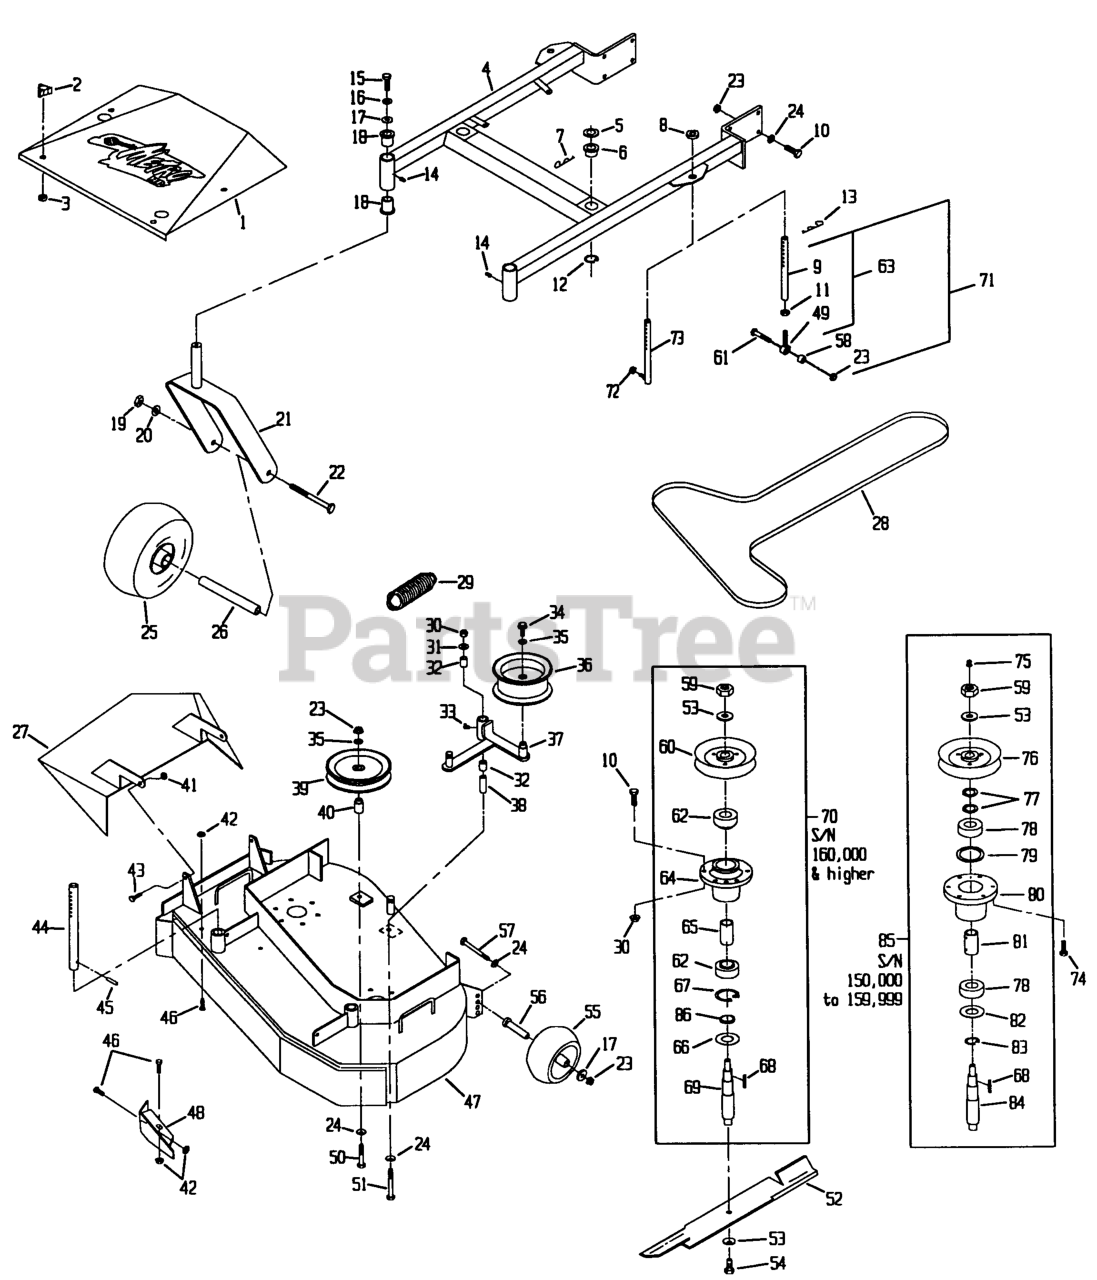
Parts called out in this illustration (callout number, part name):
1	SHIELD W/DECAL,MHP36
2	KNOB-3 PRONG
4	DECK SUPPORT W/BSHGS 36"
5	SPACER-DECK SUPPORT
6	BUSHING-DECK
9	LINK, DECK SUPPORT
13	PIN,HAIR COTTER
18	BEARING-FLANGED
28	BELT,DECK DRIVE
32	SLEEVE-BEARING
38	BUSHING-PIVOT, IDLER
39	PULLEY-IDLER
40	BUSHING-IDLER
44	ROD,DECK SUPPORT
47	ASM,DECK W/DECALS TTHP/MH
49	BALLJOINT
51	SCREW-HH
53	WASHER-SPRING
55	ROLLER-SCALP, ANTI
56	BUSHING-ROLLER
60	SHEAVE,W/HUB 5.72
62	BEARING
65	SPACER-BEARING
66	GUARD-BEARING, BOTTOM
68	KEY-RECTANGLE
69	SHAFT,SPINDLE
70	HOUSING,CUTTER COMPLETE
73	Link
74	SCRW,TPTTE HH
76	SHEAVE,W/HUB 5.72
77	WASHER-SPACER
78	BEARING,HD SPINDLE
79	O-RING
80	HOUSING,BEARING
81	SPACER,BEARING
82	SEAL,MECHANICAL DUST
83	RING,SNAP WLDS N5000-244
85	Housing, Cutter Assembly
86	SPACER-PULLEY/BEARING
